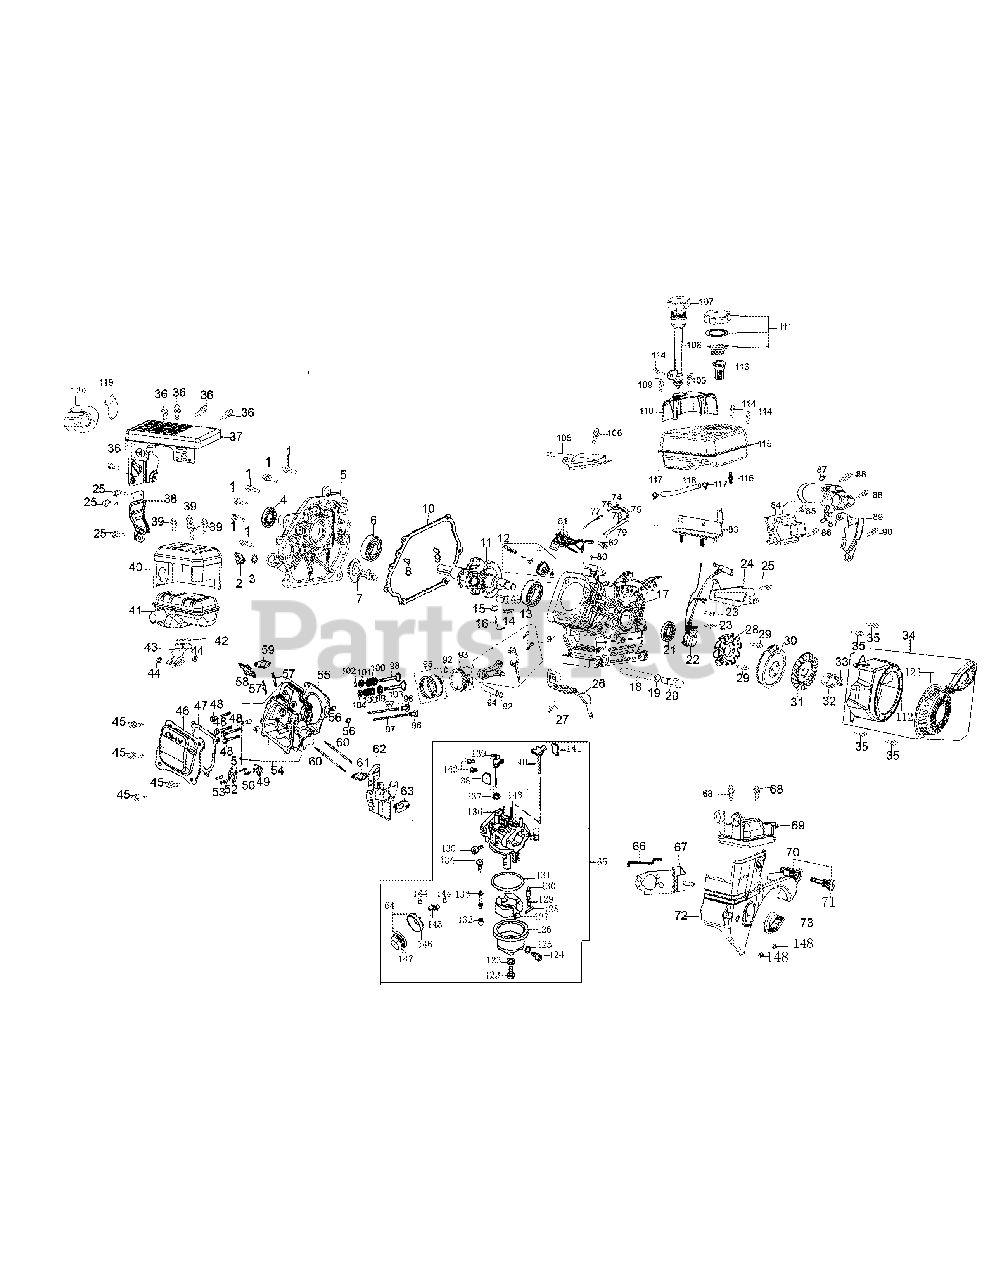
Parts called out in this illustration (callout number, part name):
1	Bolt
2	Oil Fill Plug Assembly
3	O-ring
4	Oil seal, 25 × 41.25 × 6
5	Crankcase cover
6	Radial Ball Bearing
7	Camshaft Assembly
8	Dowel Pin, 9 × 14
9	Dowel Pin, 7 × 14
10	Crankcase Cover Gasket
11	Crankshaft Complete
12	Governor Kit
13	Radial Ball Bearing
14	Pin Lock
15	O-ring, 5.2 × 1.9
16	Governor Arm
17	Crankcase
18	Oil-Draining Pipe
18	Oil Drain Assembly
19	Washer, 10 × 16 × 1.5
20	Drain Bolt, 10 × 1.25
21	Oil Seal, 25 × 41.25 × 6
22	Ignition Module
28	Stator
30	Flywheel
31	Cooling Fan
32	Starter Cup
35	Recoil Bolt
37	Muffler Shroud
40	Muffler Shield
41	Muffler Complete
42	Gasket
47	Valve Cover Gasket
49	Plate Push Rod Guide
50	Pivot Bolt
51	Rocker Arm
52	Valve Adjusting Nut
53	Pivot Locking Nut
54	Cylinder Head Complete
55	Cylinder Head Gasket
56	Dowel Pin, 10 × 16
57	Muffler Stud Assembly, 8 × 34
58	Spark Plug
59	Gasket Muffler
59	Gaske tMuffler
61	Insulator Gasket Carburetor
61	Carburetor Insulator Gasket
62	Insulator Carburetor
62	Carburetor Insulator
63	Carburetor Gasket
63	Gasket Carburetor
65	Carburetor Assembly
66	Choke Push Rod
69	Air Filter Heating Pipe Cover
70	Key Switch
71	Key
72	Shroud
73	Choke Knob
77	Spring Governor
78	Spring Throttle Return
79	Rod Governor
81	Throttle Control Assembly
82	Throttle Control Knob
84	Electric Starter, 110v
91	Connecting Rod Assembly
92	Piston Pin Clip
93	Piston
94	Pin Piston
97	Push Rod
97	Push Rod Kit
98	Exhaust Valve
98	Valve Kit
99	Valve Seal
100	Spring Valve
101	Exhaust Valve Spring Retainer
102	Exhaust Valve Adjuster
103	Intake Valve
104	Internal Valve Spring Retainer
107	Dipstick
108	Dipstick Base
110	Dipstick Decoration Cover
111	Fuel Tank Cap
112	Blower Housing
113	Fuel Filter
115	Fuel Tank
116	Nipple Fuel Tank
117	Fuel Line Kit
121	Recoil Starter Assembly
121	Starter Handle
122	Fuel Drain Plug
123	Fuel Cup Fixed Bolt Packing
124	Fuel Drain Plug
125	Fuel Drain Plug Gasket
126	Fuel Cup
127	Float
128	Floating Pin
129	Needle Valve Spring
130	Needle Valve
131	O-ring Packing
132	Main Jet
133	Main Nozzle
134	Idle Jet Assembly
135	Idle Speed Adjusting Screw
136	Carburetor Body
137	Fiber Seal
138	Choke Plate
139	Throttle Shaft
140	Choke Plate
141	Choke Shaft
142	Cross Screw
143	Position Spring
144	Clip
145	Fuel Hose
146	Primer Base
147	Primer Bulb
147	Primer
149	Woodruff Key
